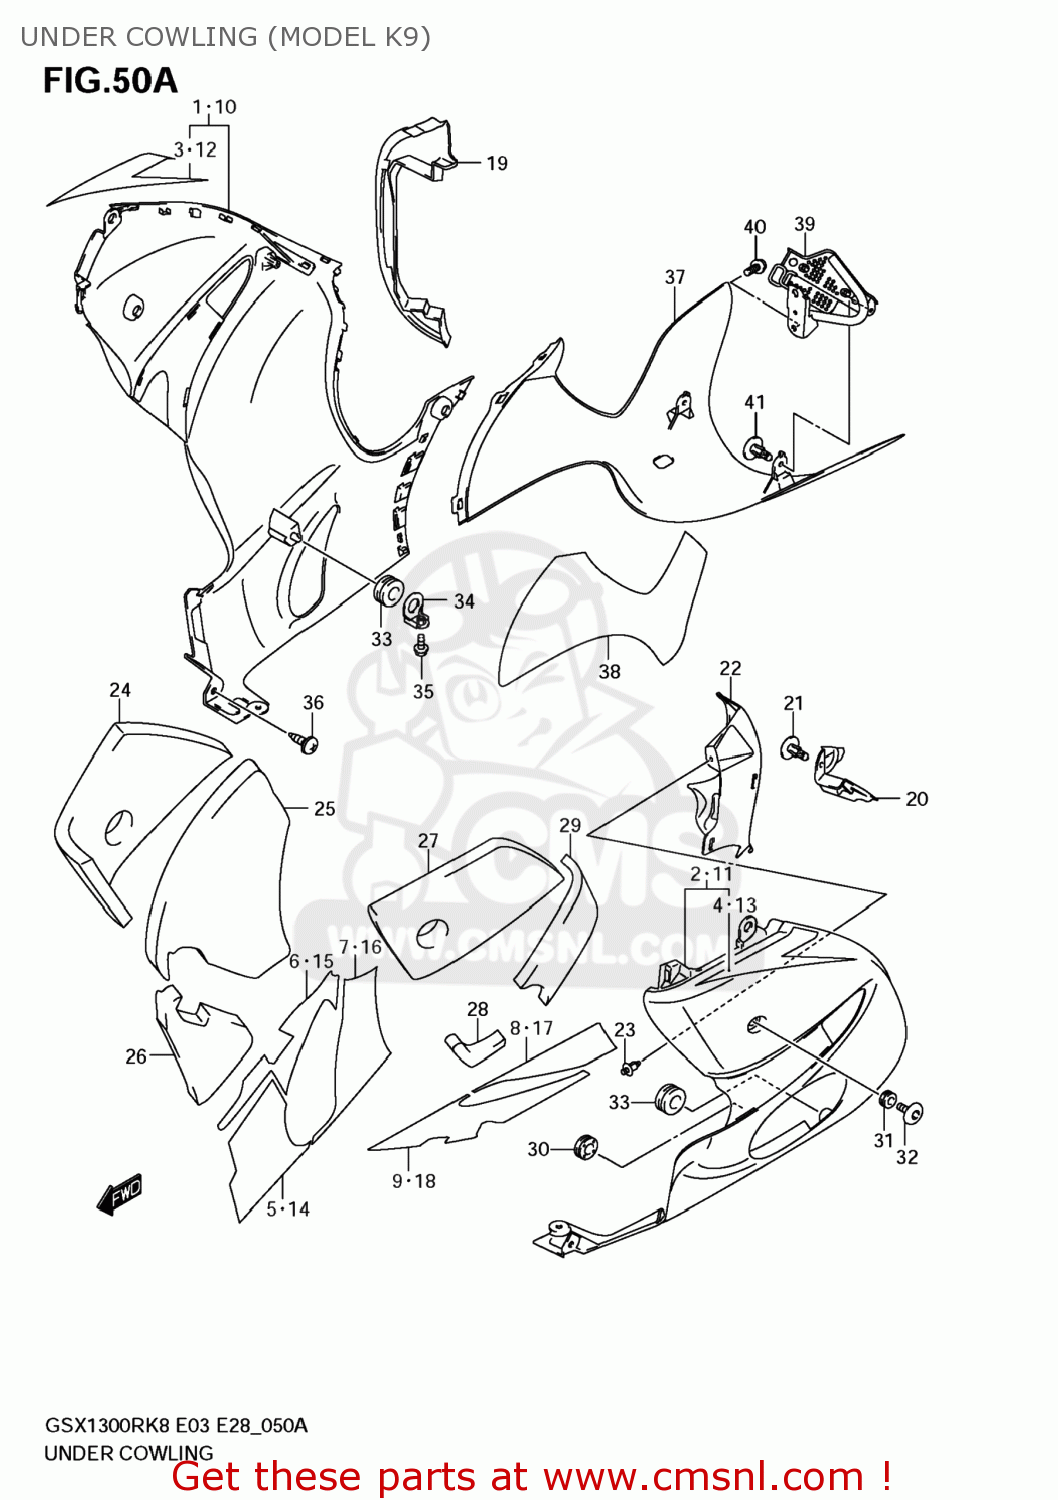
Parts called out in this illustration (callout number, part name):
1	COWLING,UNDER,R(GRAY)
2	COWLING,UNDER,L(GRAY)
3	TAPE,COWL UNDER,R
4	TAPE,COWL UNDER,L
5	SHIELD,UNDER COWL HEAT,R NO.1
6	SHIELD,UNDER COWL HEAT,R NO.3
7	SHIELD,UNDER COWL HEAT,R NO.2
8	SHIELD,UNDER COWL HEAT,L NO.1
9	SHIELD,UNDER COWL HEAT,L NO.2
10	COWLING,UNDER,R(SILVER)
11	COWLING,UNDER,L(SILVER)
12	TAPE,COWL UNDER,R
13	TAPE,COWL UNDER,L
14	SHIELD,UNDER COWL HEAT,R NO.1
15	SHIELD,UNDER COWL HEAT,R NO.3
16	SHIELD,UNDER COWL HEAT,R NO.2
17	SHIELD,UNDER COWL HEAT,L NO.1
18	SHIELD,UNDER COWL HEAT,L NO.2
19	PROTECTOR,COWLING UNDER,R
20	PROTECTOR,COWLING UNDER,L
21	CLIP
22	COVER,UNDER COWL,L
23	CLIP(BLACK)
24	CUSHION,UNDER COWLING,R NO.1
25	CUSHION,UNDER COWLING,R NO.2
26	CUSHION,UNDER COWLING,R NO.3
27	CUSHION,UNDER COWLING,L NO.1
28	CUSHION,UNDER COWLING,L NO.2
29	CUSHION,UNDER COWLING,L NO.3
30	CUSHION,UNDER COWLING,L
31	CUSHION
32	SCREW(6X20)
33	CUSHION
34	PLATE,UNDER COWL
35	BOLT
36	SCREW
37	COWLING,UNDER RR
38	SHIELD,UNDER COWL HEAT
39	BRACKET,RR UNDER COWLING
40	BOLT
41	CLIP
